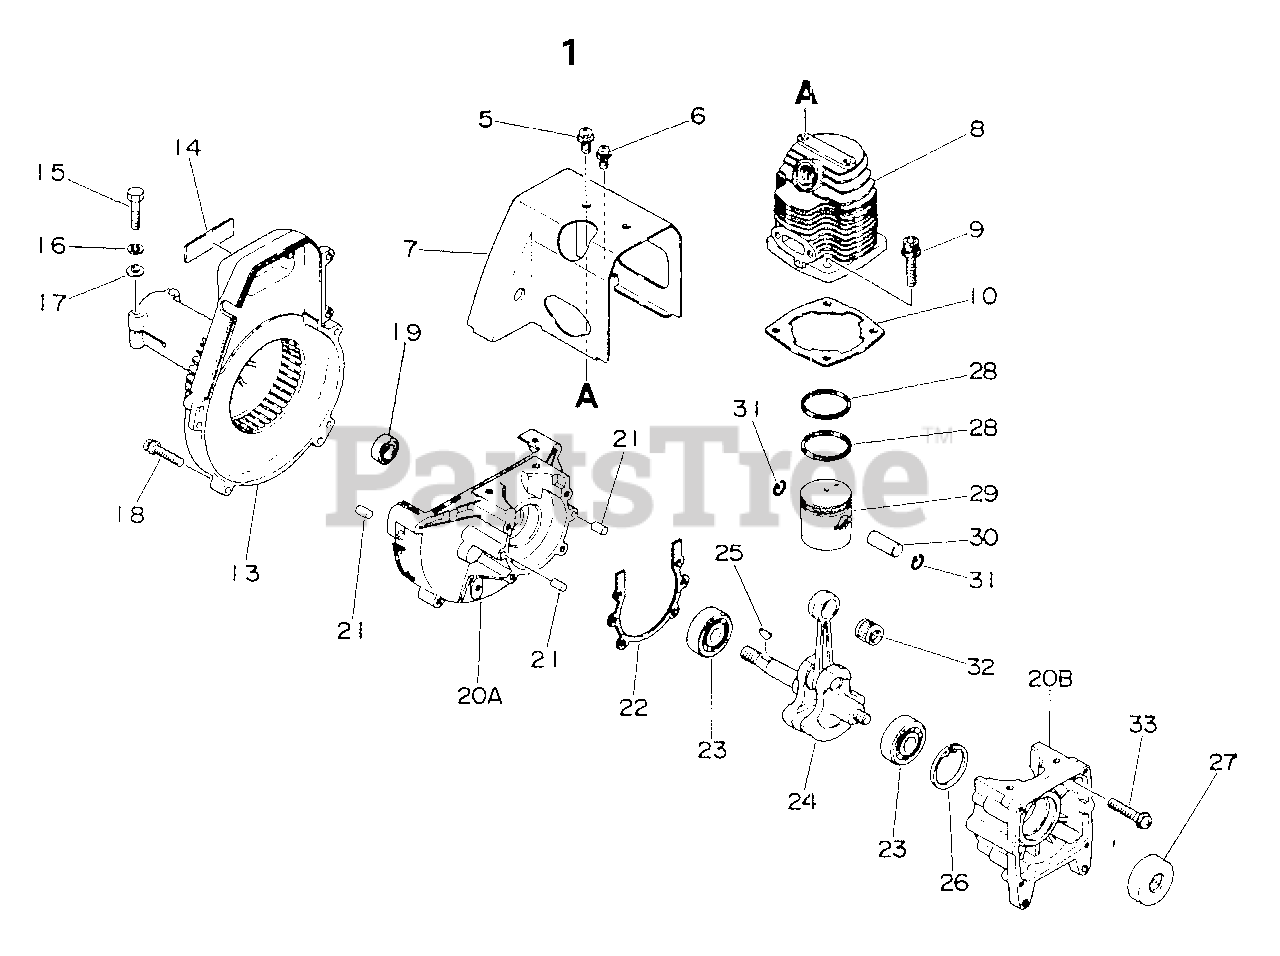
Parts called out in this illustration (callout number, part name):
5	SCREW - 5X10
6	SCREW - 4X10
7	COVER, ENGINE
8	CYLINDER
9	SCREW - 5X20
10	GASKET, CYLINDER
13	CASE, FAN
14	LABEL
15	BOLT - 5X25
16	LOCKWASHER - 5
17	WASHER - 5
18	SCREW - 5X25
19	SEAL, OIL
20	CRANKCASE KIT
20A	CRANKCASE KIT
20B	CRANKCASE KIT
21	PIN - LOCATING
22	GASKET, CRANKCASE
23	BEARING, BALL - 6202
24	CRANKSHAFT ASSY
26	RING, RETAINING - 35
27	SEAL, OIL
28	RING, PISTON
29	PISTON
30	PIN, PISTON
31	RING, RETAINING - 8
32	BEARING, NEEDLE
33	SCREW - 5X30
